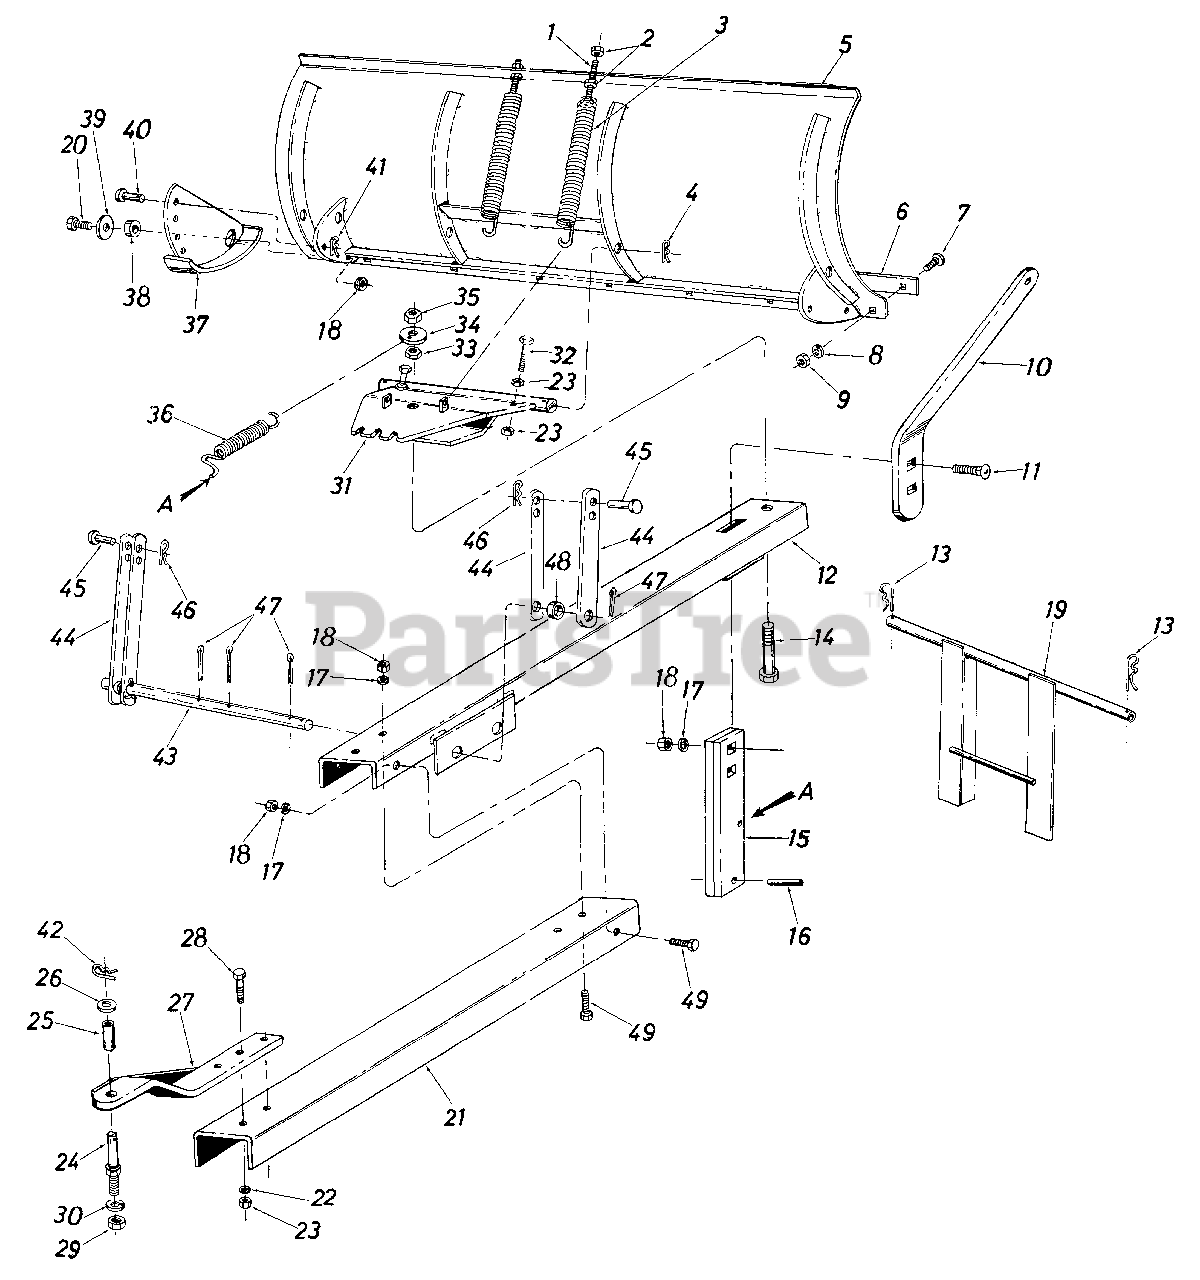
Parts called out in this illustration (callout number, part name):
1	Hex Scr. 3/8-16 x 4.50" Lg.
2	Hex Nut 3/8-16 Thd.
3	Blade Adjustment Spring
4	Hair Pin Cotter, 5/32
5	54" Blade Ass'y.
6	Wear Plate
7	Carriage Bolt 5/16-18 x .75" Lg.
8	L.-Wash. 5/16" Scr.
9	Hex Nut 5/16-18 Thd.
10	Lock Extension Bar
11	Carriage Bolt 3/8-16 x 1.25" Lg.
12	Front Push Bar Ass'y.
13	Hair Pin Cotter, 5/32
14	Hex Scr. 3/4-10 x 3.50" Lg.
15	Angle - Lock Bar
16	Spring Pin Spirol .25" Dia. x 1.00" Lg.
17	L.-Wash. 3/8" Scr.
18	Hex L.-Nut 3/8-16 Thd.
19	Guide Bracket Ass'y.
20	Hex Scr. 3/8-16 x .75" Lg.
21	Rear Push Bar Channel
22	L.-Wash. 1/2" Scr.
23	Hex Nut 1/2-13 Thd.
24	Link Clevis Pin
25	Spacer 1" O.D. x 21/32" I.D. x .75" Lg.
26	Fl-Wash. 21/32 I.D. x .090 O.D.
29	Hex Jam L.-Nut 5/8-18 Thd.
30	L.-Wash. 5/8" Scr.
31	Pivot Plate Ass'y.
32	Hex Scr. 1 /2-13 x 2.00" Lg.
33	Hex Jam Nut 3/4-10 Thd.
34	Fl.-Wash. 3/8" (Special)
35	Hex Lock Nut 3/4-10 Thd.
36	Angle Lock Spring
37	Skid Assembly
38	Bushing, Pivot Skid
39	Fl.-Wash. .385" I.D. x 1.00" O.D.
40	Clevis Pin 5/16" Dia. x 3/4" Lg.
41	Hair Pin Cotter 3/32"
42	Hair Pin Cotter, 5/32
43	Lift Shaft
44	Lift Link
45	Clevis Pin 1/2" Dia. x 1.00" Lg.
46	Hair Pin Cotter, 3/32"
47	Cotter Pin 1/8" Dia. x 1.50." Lg.
48	Spacer, Lift Link
49	Hex Scr. 3/8-16 x 1.00" Lg.
